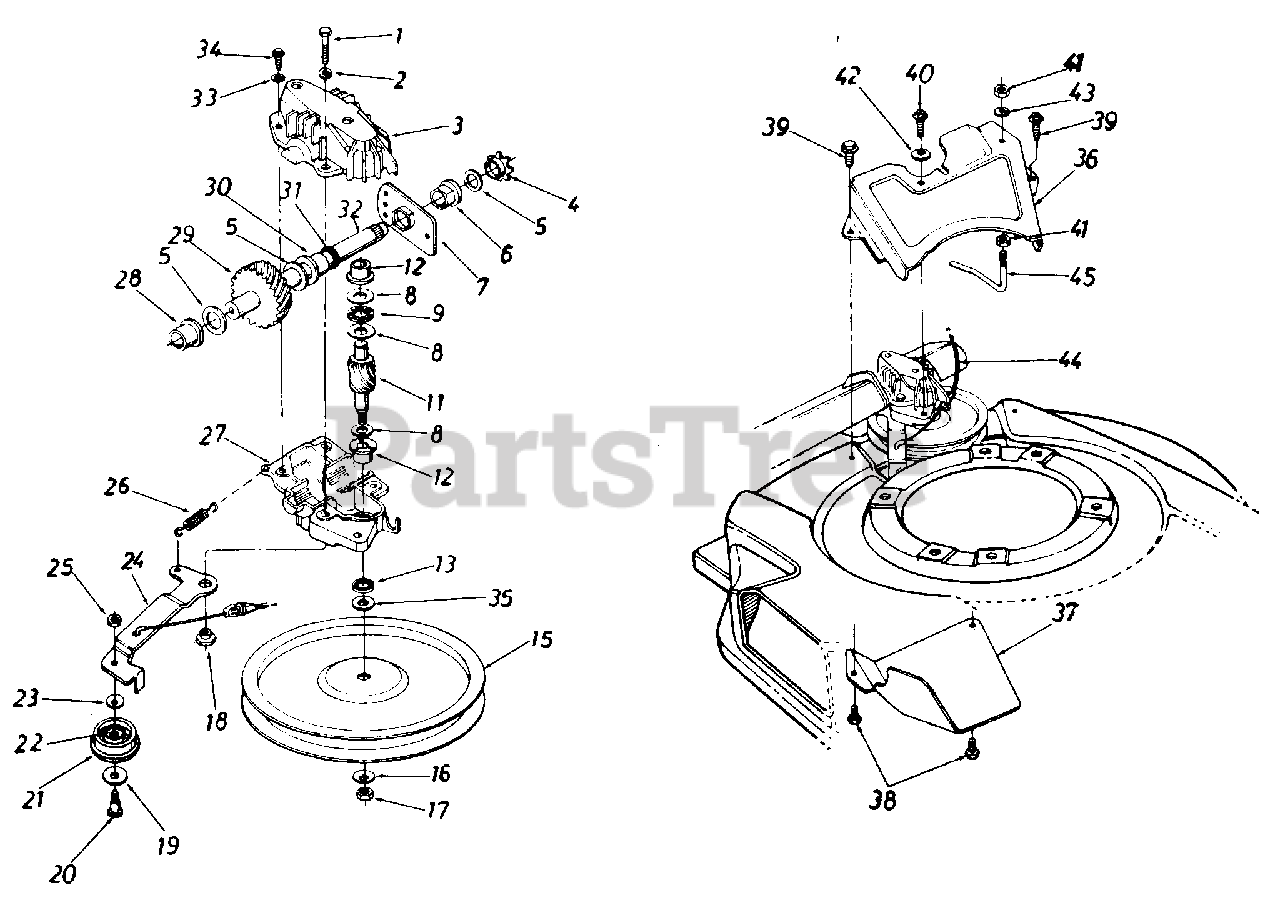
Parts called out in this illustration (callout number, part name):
1	Hex Bolt 1/4-20 x 1.25" Lg.
2	L-Wash. 1/4" I.D.
3	Upper Hsg. Half
4	#48 Sprocket 7 Tooth x 1/2 Pitch
5	Fl-Wash. 5/8" I.D. x .030
6	Hex Flange Brg. .631" I.D.
8	Thrust Wash. .382" I.D. x .70" O.D.
9	Thrust Bearing .375" I.D. x .812" O.D.
11	11 Tooth Helical Gear
12	Flange Bearing
13	Oil Seal
15	Fl-Pulley 5.06" I.D.
16	Bell-Wash. .265" I.D. x 75"
17	Hex Nut 1/4-28 L.H. Thd.
18	Shld. Spacer .375" Dia. x .170
19	Fl-Wash. .390" I.D. x 1.0"
20	Shld. Bolt .375" Dia. x .40"
21	Fl-Idler Plastic 1.50" Dia
22	Needle Brg. .375" x 375"
23	Bell-Wash. .265" I.D. x .75"
24	Idler Brk't. Ass'y.
25	Hex Patch L-Nut 1/4-28 Thd
26	Extension Spring 1.12" Lg.
27	Lower Hsg. Half
28	Flange Bearing .56 Dia.
29	33 Tooth Helical Gear
30	Flange Bearing .629 Dia.
31	Oil Seal .625 Dia.
32	Gear Sprocket Shaft
33	L-Wash. #10 I.D.
34	Hex B-Tap Scr. #10 x .62"
35	Hex Washer .26" x .88"
39	Hex AB-Tap Scr. 1/4 x .50" Lg
40	Hex B-Tap Scr. 1/4 x .62" Lg.
41	Hex Nut 1/4-20 Thd.
42	Bell-Wash. .265" I.D. x 75"
43	L-Wash. 1/4" I.D.
44	S.P. Cable-48" Lg.
45	S.P. Belt Guard
